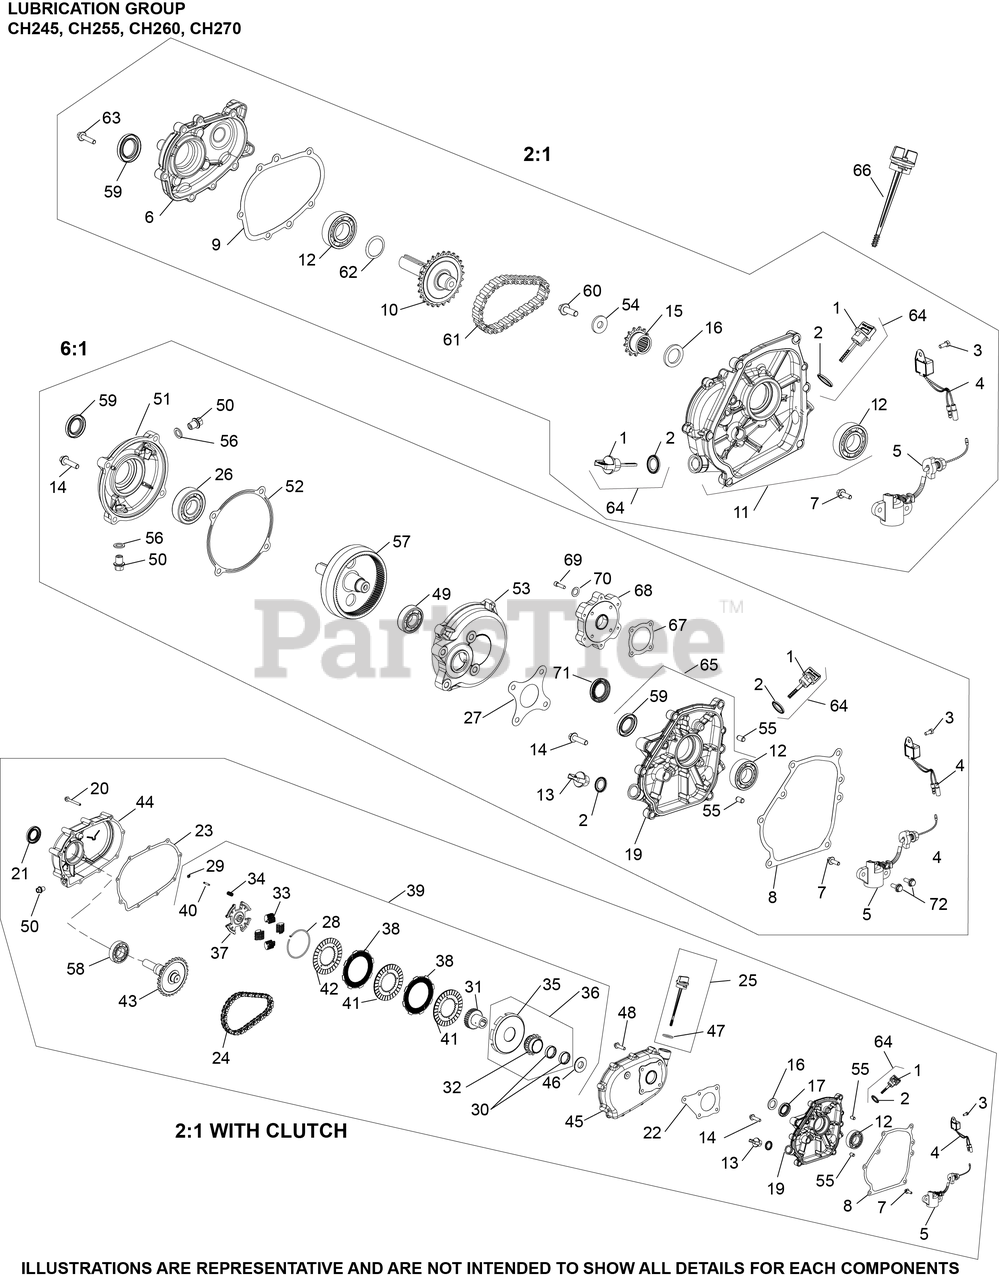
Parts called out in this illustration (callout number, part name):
2	SEAL, OIL
12	BEARING, BALL
14	SCREW, CLOSURE PLATE
17	SEAL- USE 17 032 29-S
19	PLATE, CLOSURE & BEARING
55	PIN, DOWEL (8MM)
64	DIPSTICK ASSEMBLY
72	SCREW, M6 X 16
